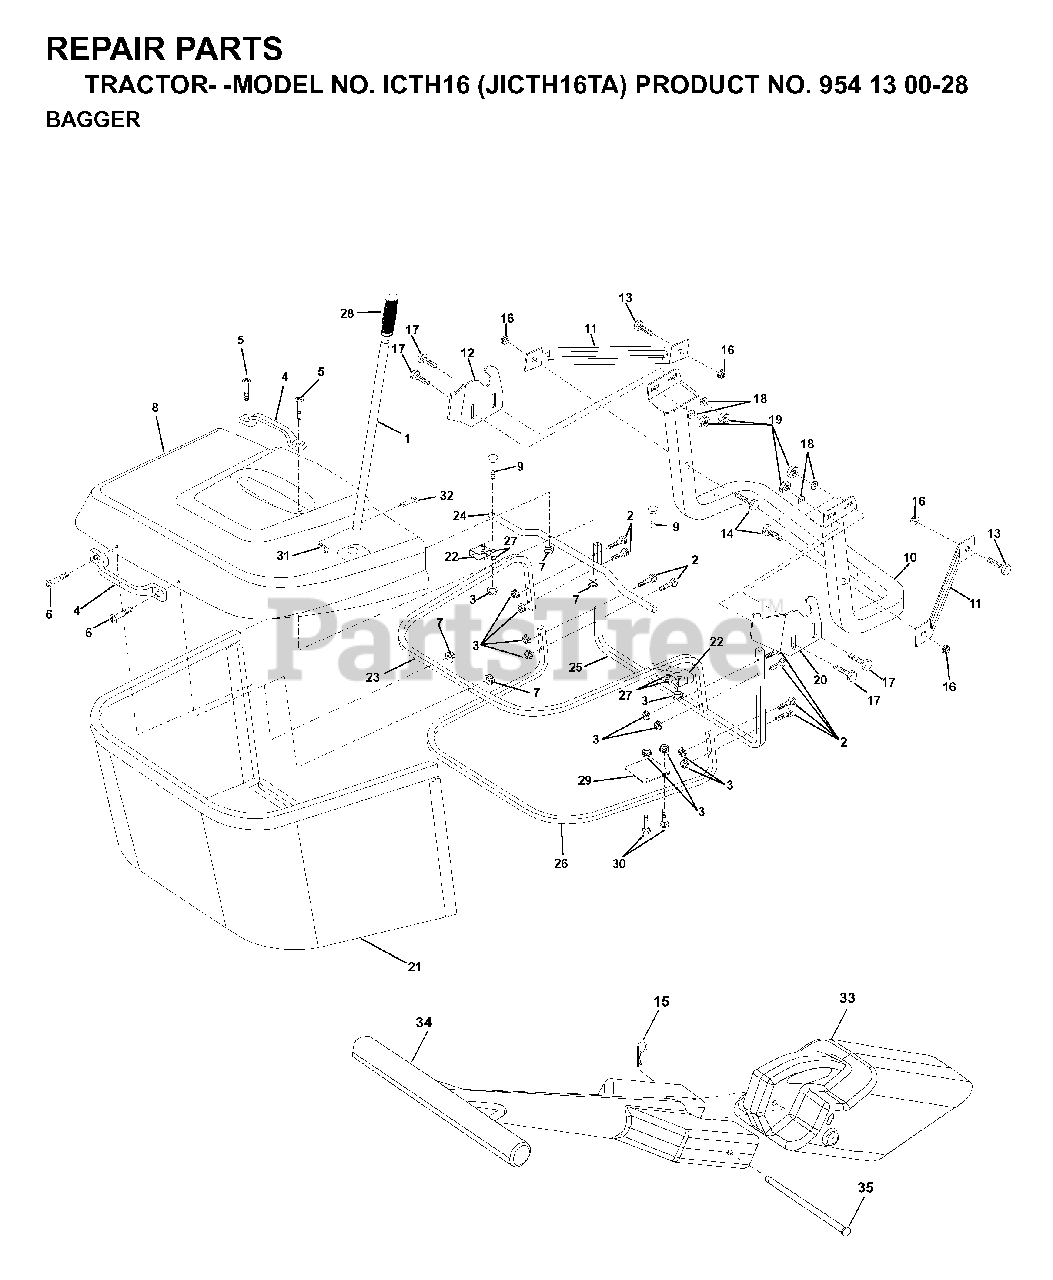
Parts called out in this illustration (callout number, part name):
1	TUBE HANDLE
3	NUT T
5	SCREW.PAN.HEAD
11	BRACKET
15	RETAINER-SPRNG RB
16	NUT LOCK FLG 3/8-16 UNC
17	BOLT
19	NUT.71038.31-18.HEX.NYLOCK
21	BAG
22	BRACKET
23	TUBE
24	TUBE
26	TUBE
28	GRIP.HANDLE.BLACK
31	RETAINER M
32	RIVET,DRILLED
33	PLUG
35	PIN
